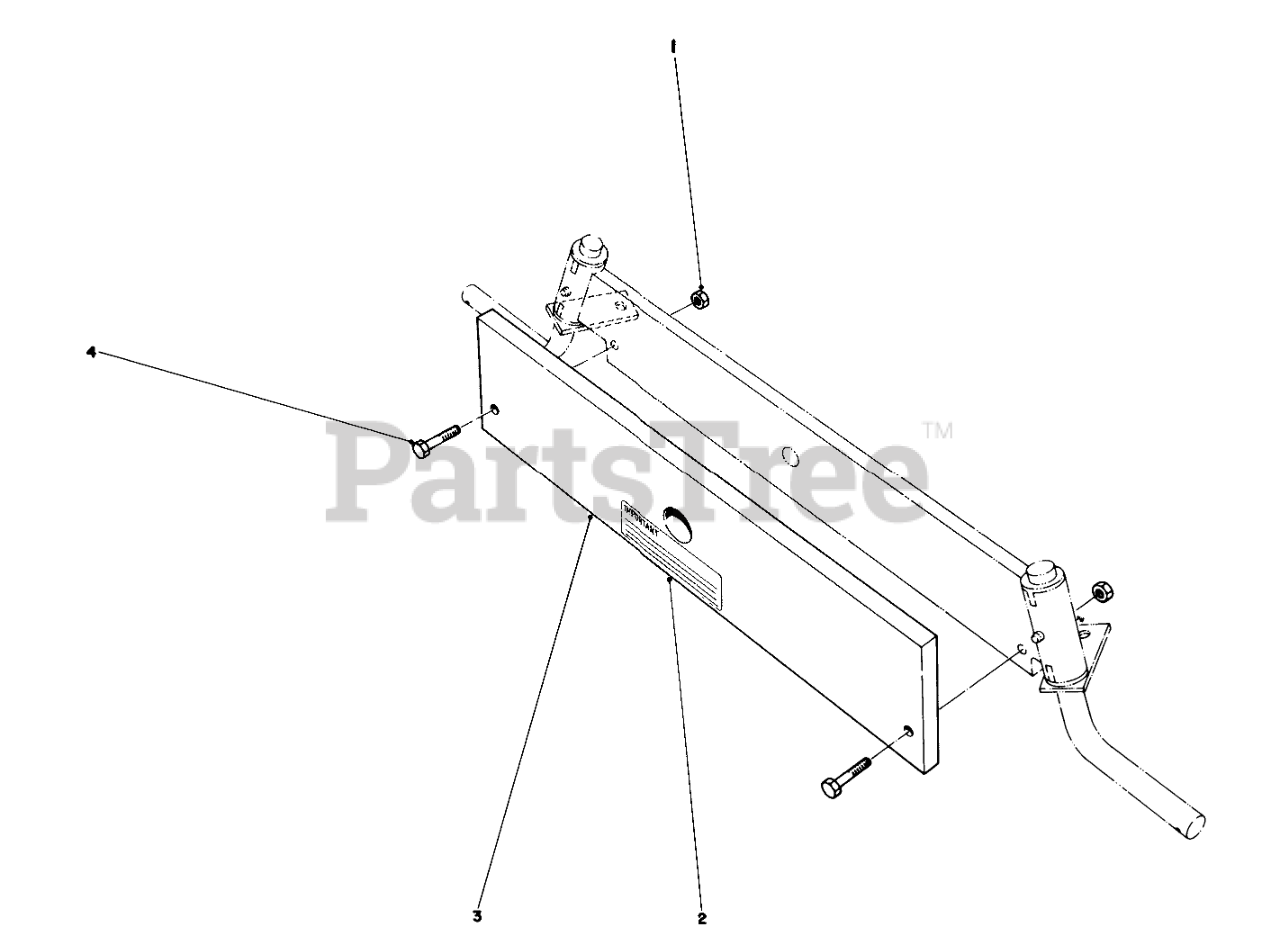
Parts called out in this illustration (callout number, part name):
1	NUT-LOCK, CONE
2	Decal-Warning
3	COUNTERWEIGHT B
4	SCREW-HH
